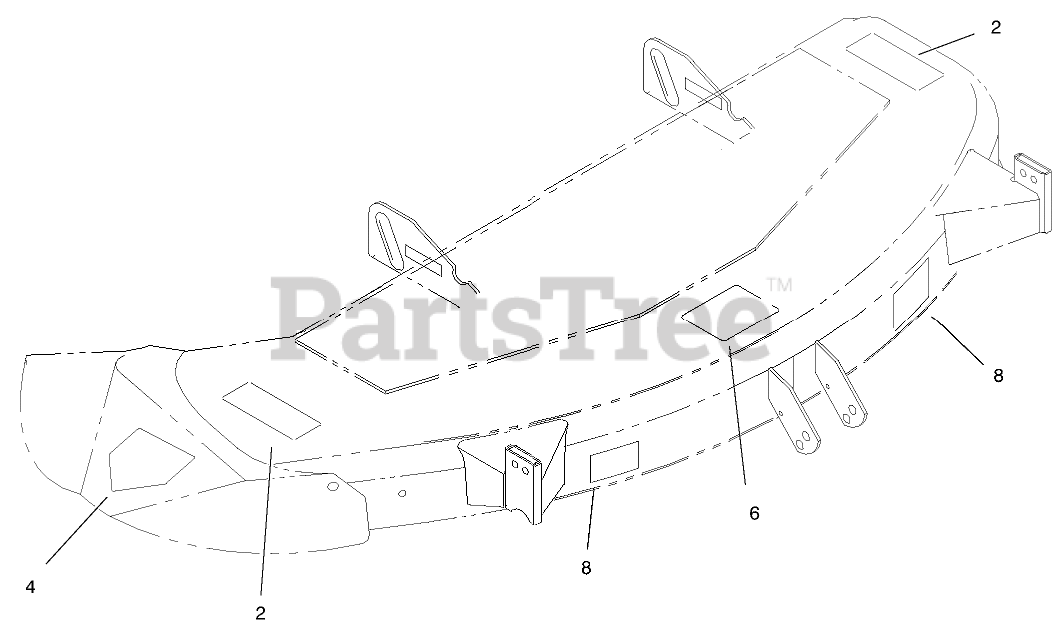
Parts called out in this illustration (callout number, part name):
2	DECAL-DANGER
4	DECAL-DANGER
6	DECAL - BELT INSTALLATION
8	DECAL-ADJUSTMENT, WHEEL
